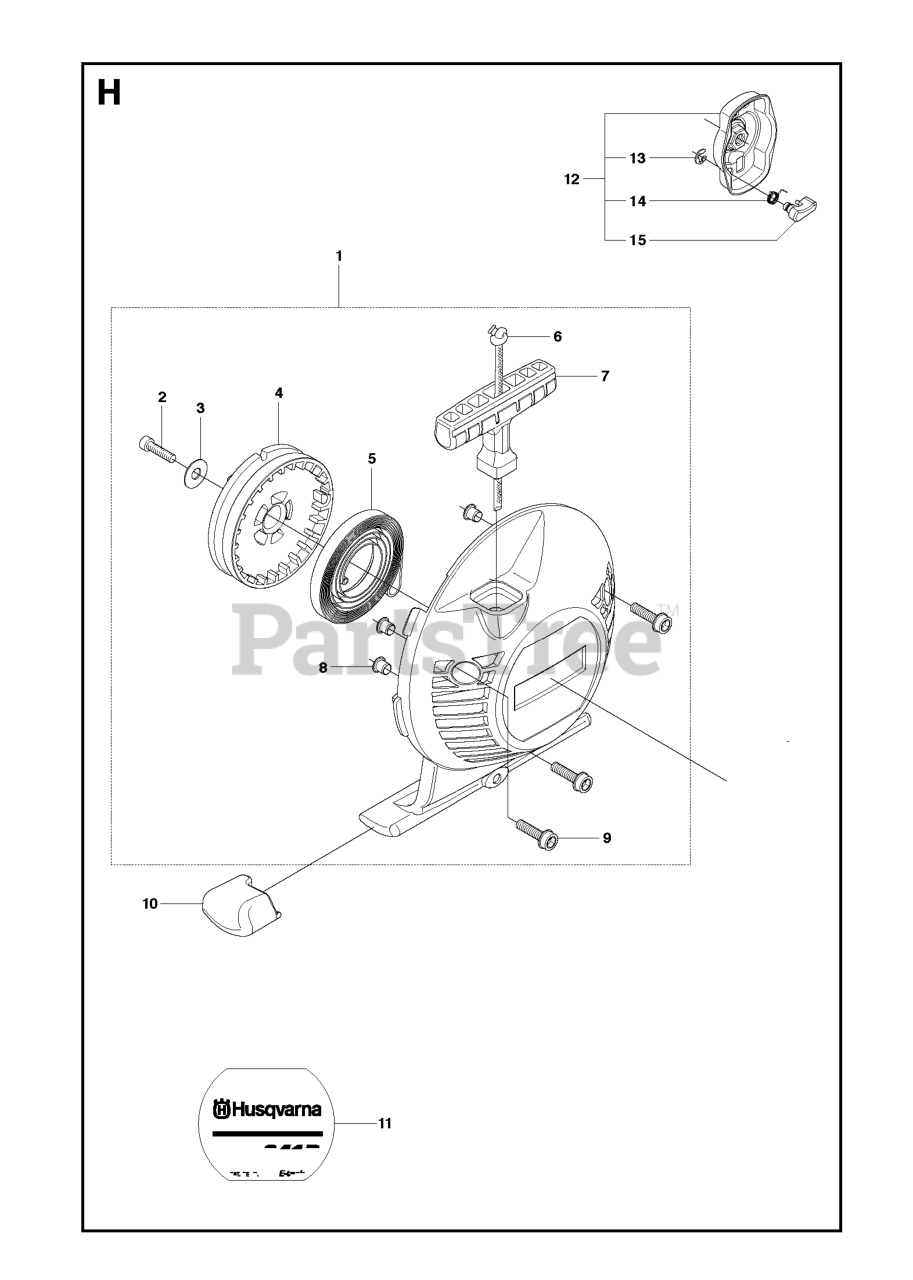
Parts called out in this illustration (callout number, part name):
1	RP STARTER ASSY
4	STARTER PULLEY
5	STARTER SPRING
7	STARTER HANDLE
9	SCREW IHSCFM
12	PAWL
15	STARTER PAWL
